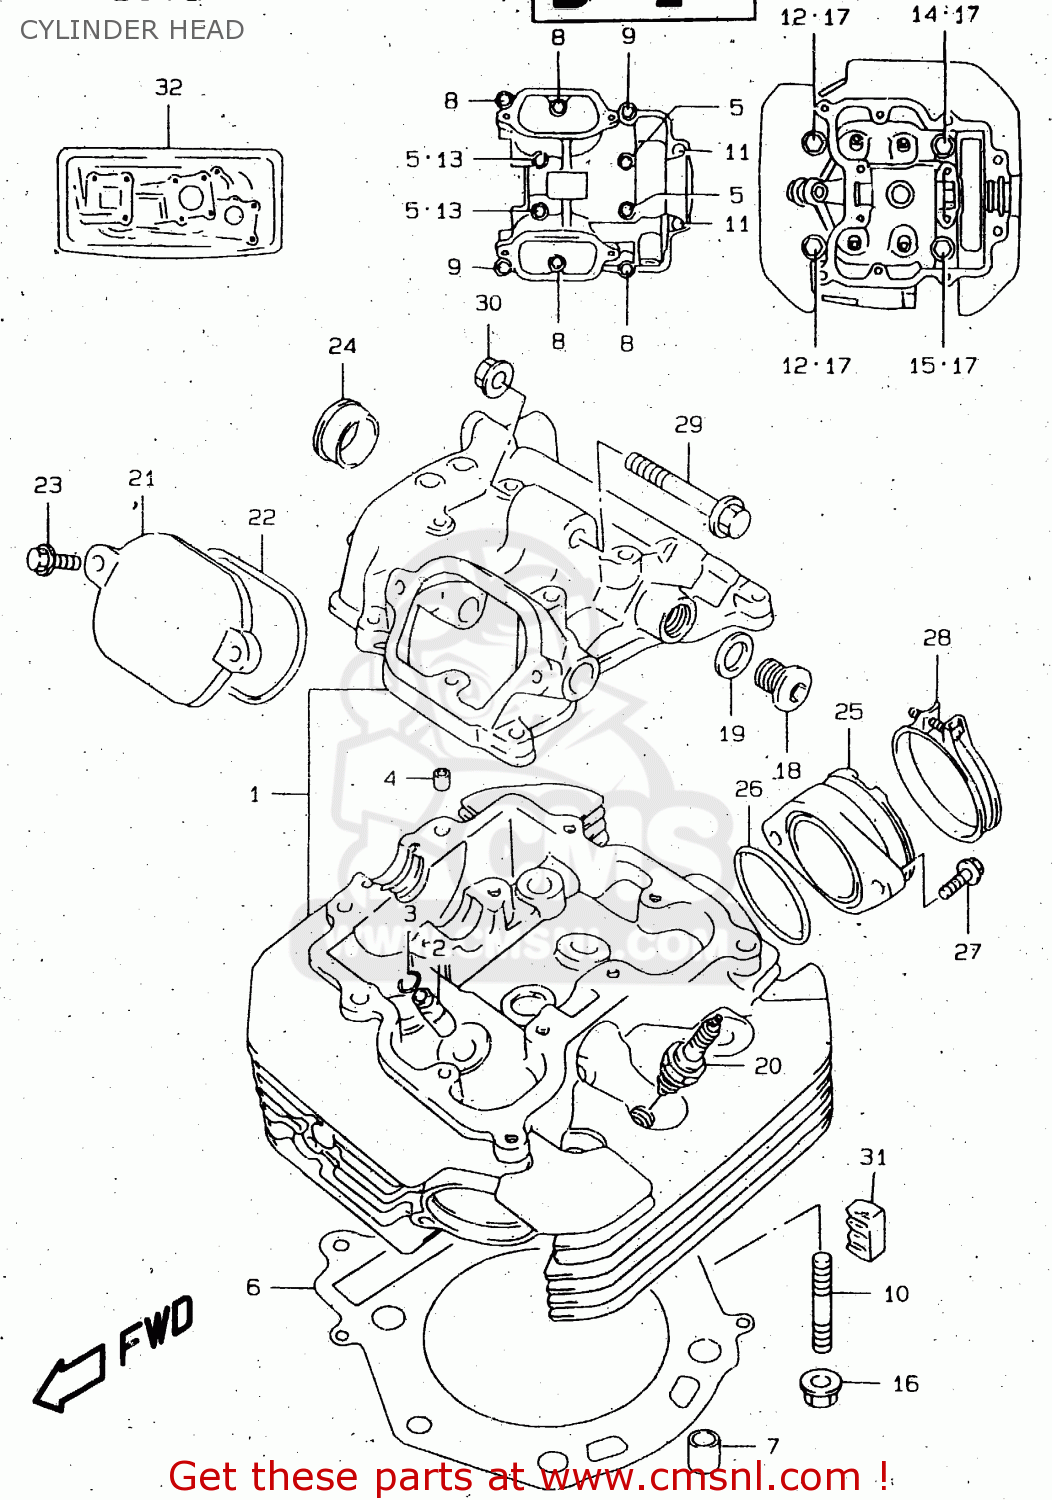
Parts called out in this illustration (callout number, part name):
1	HEAD ASSY,CYLINDER
2	GUIDE,VALVE
3	RING,SNAP
4	PIN(6.2X8X11)
5	BOLT(6X55)
6	GASKET,CYLINDER HEAD
7	PIN
8	BOLT
9	BOLT
10	BOLT,STUD
11	BOLT(6X115)
12	BOLT(10X180)
13	GASKET(5.8X13X1.2) (NAS)
14	BOLT(10X190)
15	BOLT(10X200)
16	NUT
17	GASKET(10.5X22X2) (NAS)
18	PLUG,14X12
19	GASKET(13.8X18.8X4.8) (NAS)
20	PLUG,SPARK(CR10E)
21	CAP,INSPECTION
22	O RING,INSPECTION CAP
23	BOLT
24	PLUG,OD:30
25	PIPE,INTAKE
26	O RING(D:2.4,ID:45.7)
27	SCREW(6X16)
28	CLAMP
29	BOLT(8X53)
30	NUT
31	PAD,CYLINDER HEAD RUBBER
32	GASKET SET (NAS)
